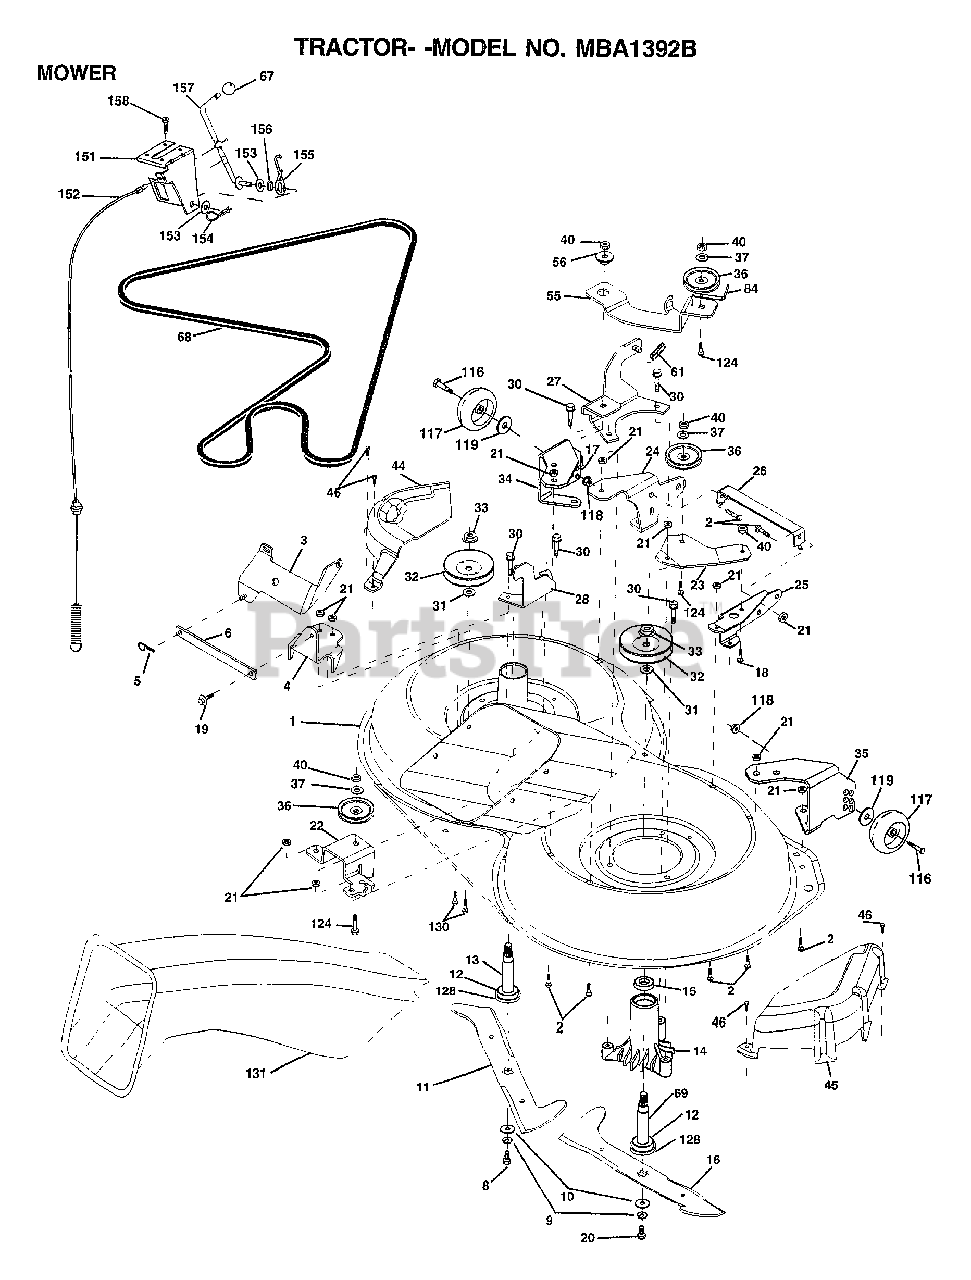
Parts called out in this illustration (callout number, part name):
1	HOUSING.ASM.MOWER
2	BOLT
3	BRKT.ASM.S-BAR.CHASSIS
4	BRKT.BAR.SWAY.DECK
6	BAR.SWAY.92.CRD
8	BLADE BOLT
10	WASHER.HARD.BLADE
11	BLADE.3-1.LH.92.CRD
12	BEARING.BALL
14	HSG ASM MANDREL
15	BEARING
16	BLADE
17	BOLT.3/8-14X1.25
18	BOLT D
19	BOLT SHD 5/16-18
20	BOLT.3/8-24X1.25
22	BRKT.IDLER.SPRT.CRD
23	"BRKT.IDLER.SPRT.RF.92,CRD"
24	BRKT.SUSP.LF.92.CRD
25	BRKT.SUSP.RF.92.CRD
26	BRACE.SUPT.SUSP.FRT.CRD
27	BRKT.ASM.SUSP.RR.92.CRD
28	BRKT.ASM.SUSP.LR.92.CRD
30	"SCREW-THD ROLL,WA"
31	WASHER
32	PULLEY.MAND.36/46
34	BRKT.GUAGE.WHL.LF.92.CRD
35	BRKT.GUAGE.WHL.RF.92.CRD
36	PULLEY.IDLER.4.25
37	WASHER
44	COVER.MANDREL.LH.92.CRD
45	COVER.MANDREL.RH.92.CRD
46	SCREW.1/4-20X5/8
55	ARM.IDLER.92.CRD
56	SPACER.RETAINER.MOWER
61	SPRING.TENSION.BELT
67	KNOB T(3/8 HOLE)
68	HEX-BELT.92.MWR.105AA
69	SHAFT.ASM.W/LWR.BRG.RH.THD
84	"KEEPER-BELT,IDLER"
116	BOLT.SHOULDER
117	WHEEL GAGE DONUT
118	LOCKNUT
119	WASHER
124	BOLT.3/8-16X1.50
128	WASHER.FELT.
131	CHUTE.BAGGER.CRD
151	BRKT CLUTCH CABLE
152	CABLE CLUTCH CRD SERVICE
153	WASHER FLAT
154	SPRING RETAINER
155	SPRING RETENTION LVR CLUTCH CAB
156	SPACER
157	ROD.CLUTCH.CABLE.3/8
158	SCREW LT
